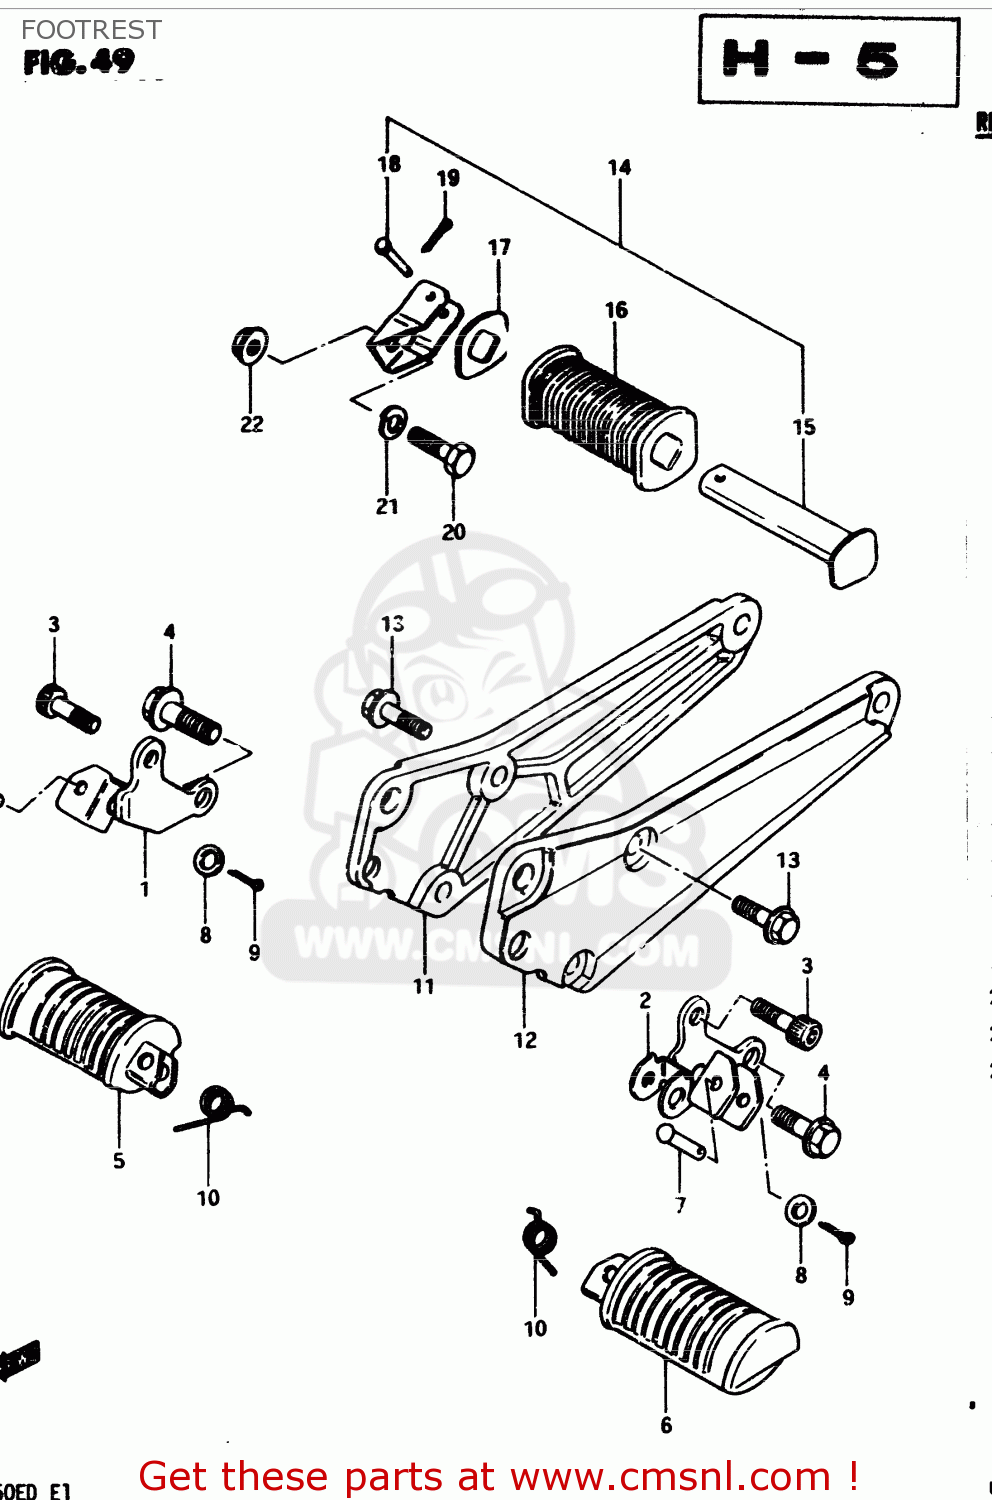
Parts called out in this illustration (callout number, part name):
1	BAR,FR FOOTREST,R
2	BAR, FOOTREST LH
3	BOLT
4	BOLT
5	RUBBER,FRONT FOOTREST
6	FOOTREST
7	PIN
8	WASHER
9	PIN 20X20
10	SPRING
11	BRACKET,MUFFLER,RIGHT
12	BRACKET,MUFFLER,LEFT
13	BOLT
14	FOOTREST ASSY,PILLION,R
15	BAR,REAR FOOTREST,LEFT
16	RUBBER,PILLION FOOTREST
17	WASHER,FOOTREST RUBBER
18	PIN
19	PIN 20X20
20	BOLT,M10X1.25X
21	LOCK WASHER
22	NUT
